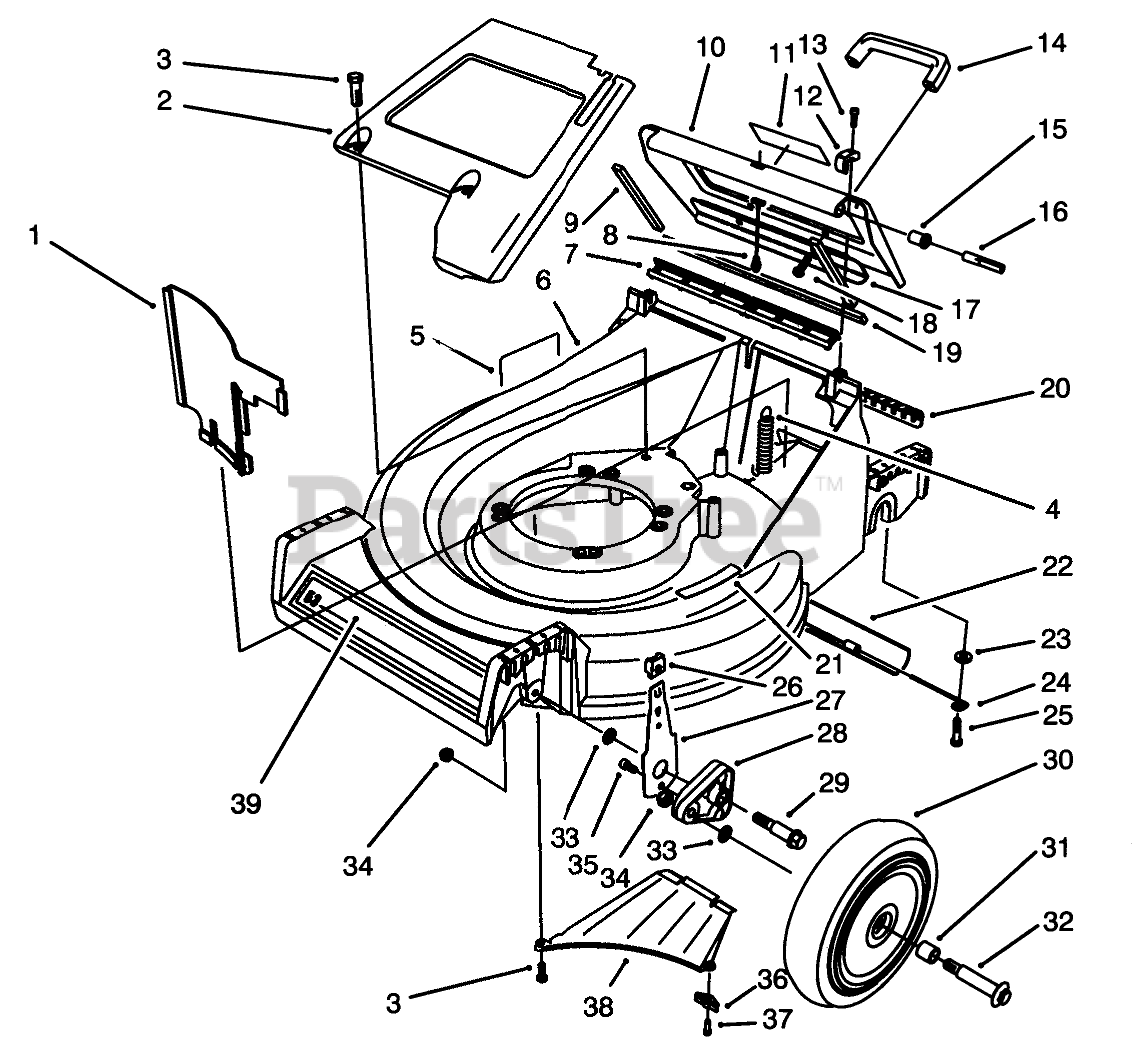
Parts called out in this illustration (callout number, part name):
1	PANEL-VERTICAL
2	PaneI-Screen
3	SCREW-HWHTF
4	EXTENSION-SPRING
5	Decal Danger
6	Housing-53cm (Incl. Ref. #5, & 21)
7	DOOR SEAL
8	DOOR CABLE
9	DOOR SIDE SEAL
10	Door-Discharge (Incl. Ref. #9, 11, 17, & 19)
11	DECAL - DANGER
12	HINGE CLAMP
13	SCREW-HSH
14	HANDLE-DOOR
15	DOOR BUSHING
16	HINGE PIN
17	DOOR - BRACE
18	SCREW-HWH
19	DOOR END SEAL
20	ACCESS COVER
21	DECAL - STEP PAD INT'L
22	TRAILING SHIELD
23	WASHER-PLAIN
24	SHIELD HANGER
25	SCREW-SHOULDER
26	KNOB-ARM
27	FRONT SPRING ARM ASM
28	ARM-PIVOT, FRONT
29	BOLT-SHOULDER
30	Wheel & Tire Assembly (Incl. Ref. #31)
31	BUSHING
32	WHEEL BOLT
33	WASHER
34	NUT-LOCK
35	SCREW-HSH, THREAD FORMING
36	Bracket-Discharge
37	SCREW-HWHTF
38	Ramp Discharge
39	DECAL
